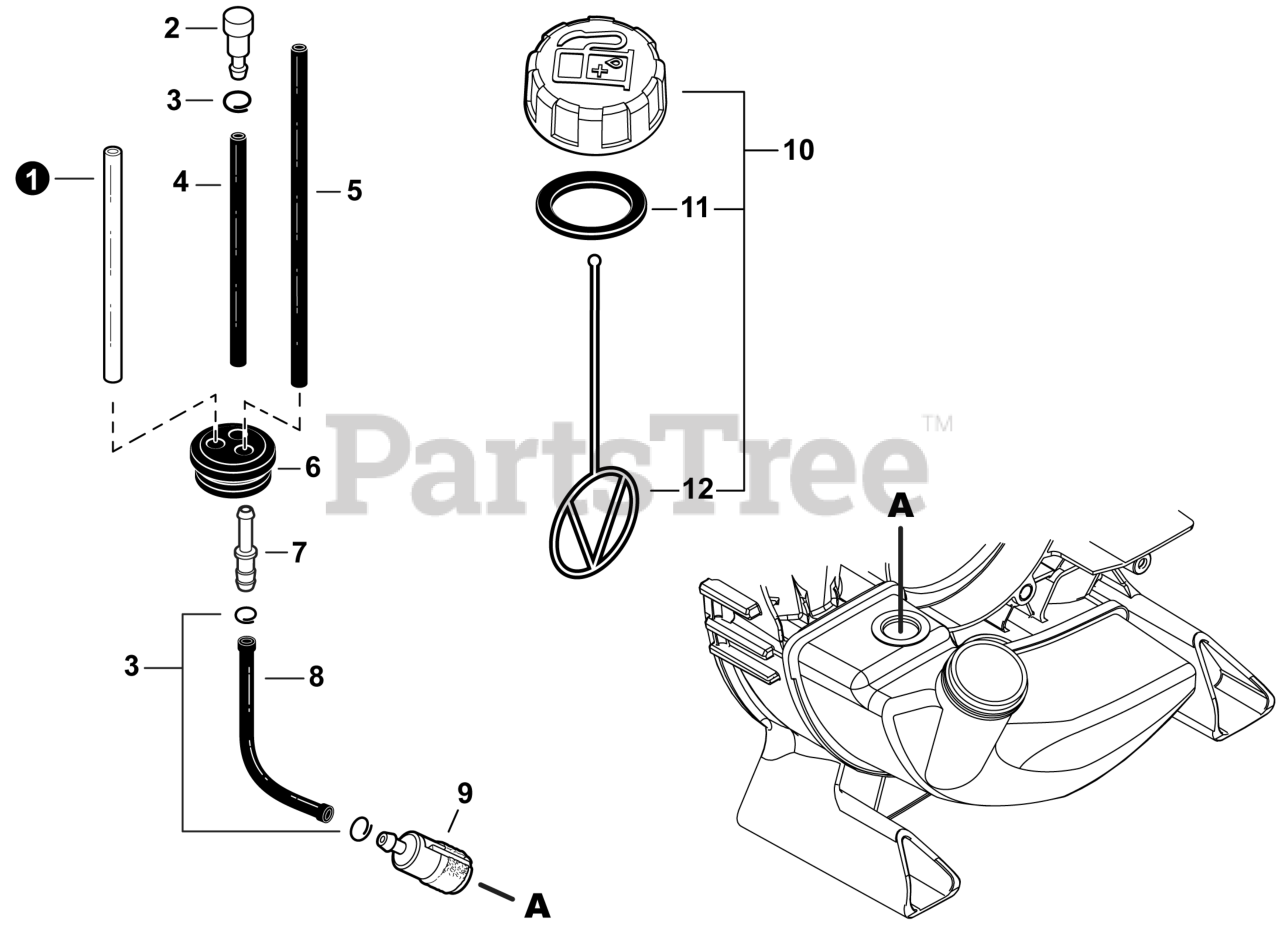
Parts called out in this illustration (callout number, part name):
1	PIPE, FUEL 3×6×85 CLEAR
2	VENT ASSY
3	CLIP Ø6
4	PIPE, FUEL 3×5×60 BLACK
5	PIPE, FUEL 3×5.5×80 BLACK
6	GROMMET, FUEL Ø5
7	CONNECTOR, PIPE Ø5ר3.5
8	PIPE, FUEL 3×5×140 BLACK
9	FILTER, FUEL
10	CAP ASSY, FUEL
11	GASKET, FUEL CAP
12	CONNECTOR, CAP L= 100 MM
